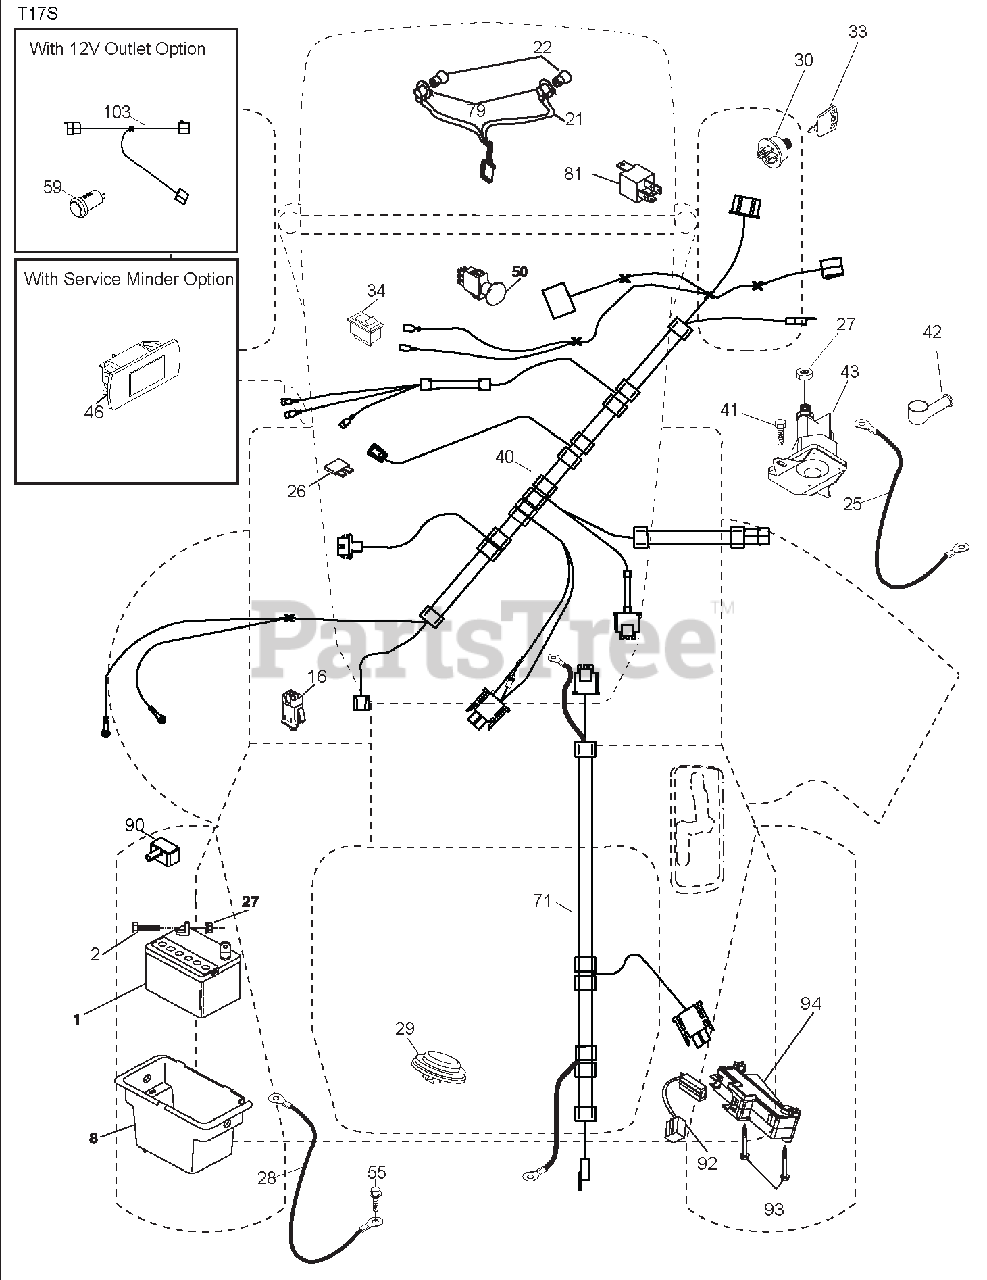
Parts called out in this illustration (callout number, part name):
1	BATTERY.12.VOLT.28.AMP.WET
2	BOLT.HEX.HD.1/4-20UNC X 3/4
8	BOX.BATTERY.MNT.REAR.LT.TEX.BL
16	SWITCH.INTERLOCK.NONO.GRAY
21	HARNESS ASM.LIGHT.22"(4152J)
22	BULB.LIGHT.#1156
25	CABLE STARTER 6 G4. BL/RED14.5
26	FUSE.20 AMP.
27	Nut, Keps Hex 1/4-20 unc
28	CABLE.BLACK.22"REAR BATT.TEX
29	SWITCH.SEAT.DELTA.OPC.9LB.
30	SWITCH.IGN.DLTA.P-IN.ROS
33	KEY/CHAIN.BLISTER PACK.GEN.USA
34	SWITCH.LIGHT/RESET.B/B/RED.
40	HARNESS IGN ELEC RELAY
41	Screw 1/4-20 x 1/2
42	COVER.TERMINAL.RED
43	SOLENOID.W/BRASS PLUNGER.2005
50	SWITCH.PTO.8 TERMINAL.BLACK
55	SCREW.5/16-18X3/4.SMGML.TAP/R
71	HARNESS.IGN.CHASS.TEX.REAR.BAT
79	SOCKET ASM.BULB.TWISTLOCK
81	RELAY HARNESS SEALED
90	COVER TERMINAL BATTERY FR. TEX
92	HARNESS.PIGTAIL.CONSLE.ROS.MLK
93	SCREW.PLASTITE.10-14 X 2.0
94	MODUAL REVERSE ROS
